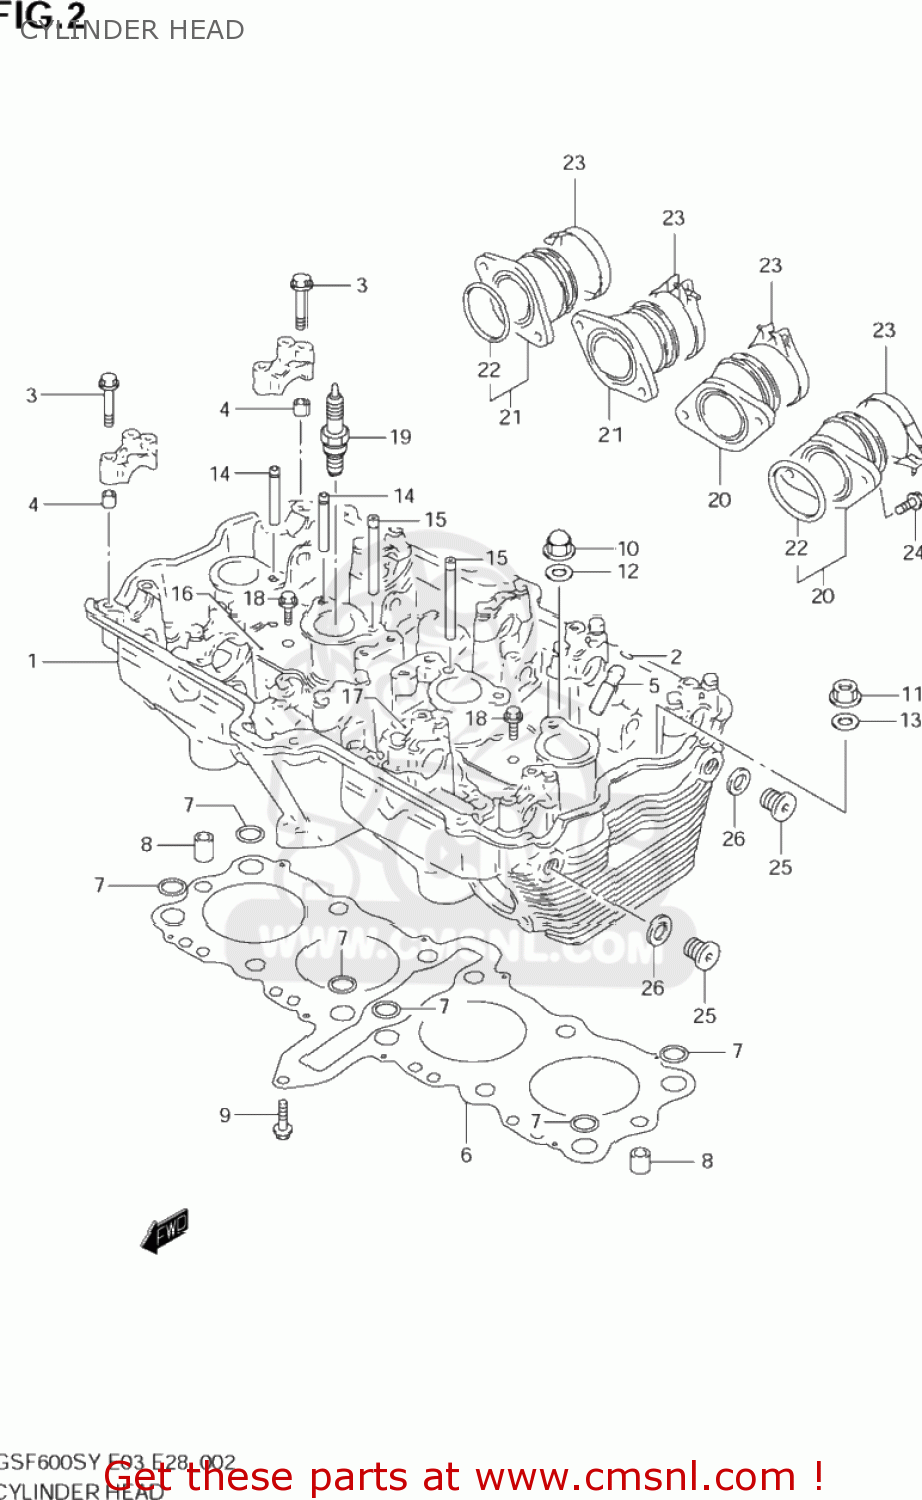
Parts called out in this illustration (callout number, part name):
1	HEAD ASSY,CYLINDER
2	RING,SNAP
3	BOLT(6X39)
4	PIN(6.2X8X11)
5	GUIDE,VALVE
6	GASKET,CYLINDER HEAD (NAS)
7	O RING(D:2.6,ID:12.1)
8	PIN
9	BOLT
10	NUT
11	NUT
12	GASKET(10.2X20X2).3 (NAS)
13	WASHER (10.5X22X2.3)
14	PIPE,OIL NO.1
15	PIPE,OIL NO.3
16	PLATE,OIL PIPE,R
17	PLATE,OIL PIPE,L
18	BOLT
19	PLUG,SPARK(CR9EK)
20	PIPE ASSY,INTAKE,L
21	PIPE ASSY,INTAKE,R
22	O RING(D:2.4,ID:39.7)
23	CLAMP
24	BOLT MAGNETO S
25	PLUG
26	GASKET(13.8X18.8X4.8) (NAS)
